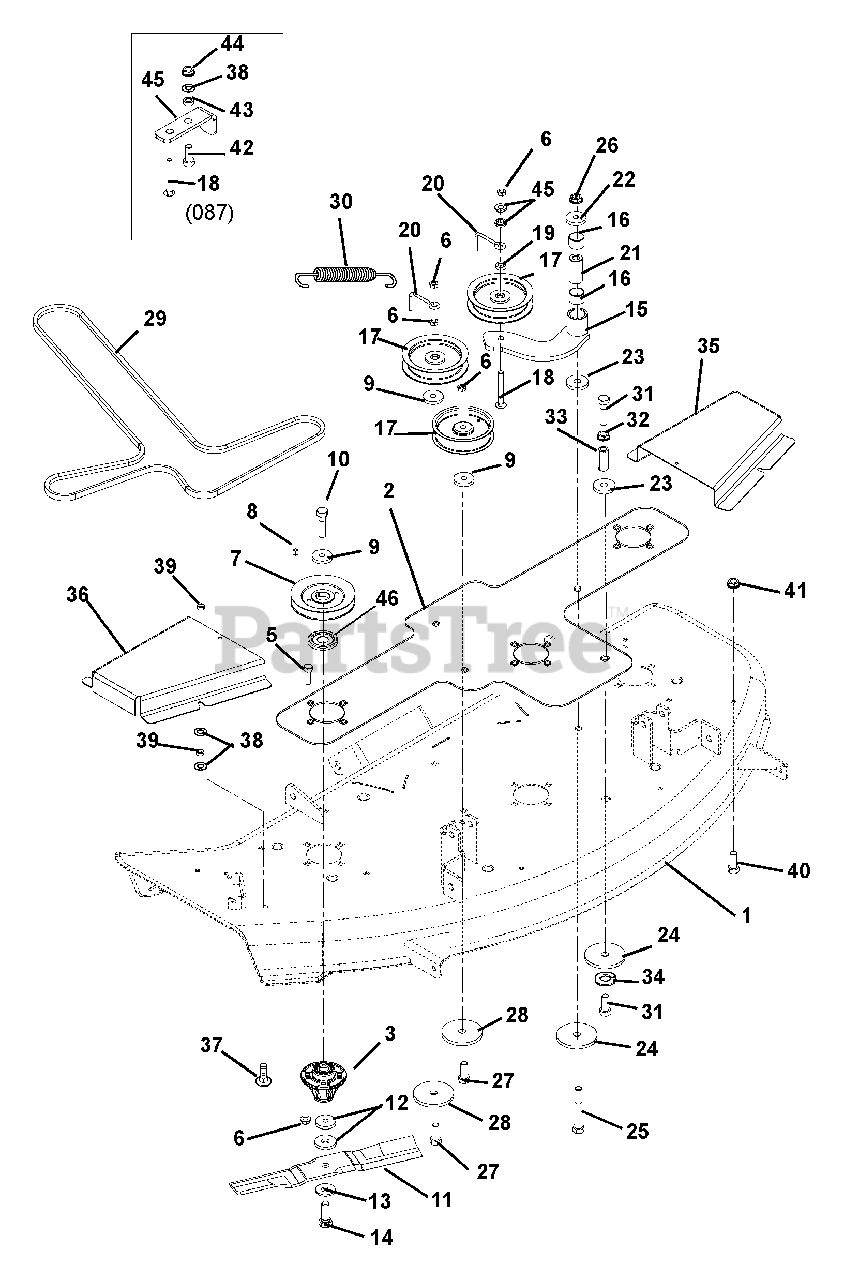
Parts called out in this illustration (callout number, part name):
1	WELDMENT, ZOOM 50" DECK
1	WELDMENT, 40" STAMPED DECK
2	50 DOUBLER PLATE, ZOOM
2	DOUBLER PLATE, ZOOM 40
3	SPINDLE ASSEMBLY
4	DUST CAP
5	@BLT-RDHDSQNK .38-16X1.25 G5YZ
6	@NUT-LK-NYL-FLG .38-16 YWZC
7	SHEAVE, 4.75 DIA A-SECTION
7	SHEAVE, 4.25 DIA A-SECTION
8	KEY, SQ .25 X .38 X .25
9	WSHR,FLT STL.406X1.50X.245YWZC
10	BLT-HEX .38-16X1.0 GR8 YZ EP30
11	BLADE
11	MOWER BLADE, 13.94"
12	WSHR-FLT .640X1.75X.250 YWZC
13	WSHR-BLVL .669X1.535X.138
14	BLT-HEX .62-18X1.75 GR8 YWZC
15	WMT, IDLER ARM
16	BRG, 1.00 X 1.12 X .75
17	IDLER, FLAT .38X4.00X1.06
18	@BLT-RDHDSQNK .38-16X3.50 G5YZ
18	@BLT-RDHDSQNK .38-16X2.50 G5YZ
19	BSHG-SLV .391X.688X.52 PM
20	BELT FINGER
21	BSHG, SPCR .502X.997X2.03 PM
22	WSHR-FL-STL.511X1.441X.125 YWZ
23	WSHR-FL-STL .515X1.625X.250 YZ
24	WASHER, FLAT .531X3.000X.25
25	@BLT-HEX .50-13X3.50 GR5 YWZC
26	@NUT-LK-TOP-FLG .50-13 YWZC
27	@BLT-HEX .38-16X2.75 GR5 YWZC
28	WSHR-FL-STL .469X2.00X.25 YWZC
29	V-BELT, A-WRAPPED
29	V-BELT, HA-WRAPPED
30	EXTENSION SPRING
31	@BLT-HEX .50-13X1.25 GR5 YWZC
32	NUT-SPNLK-FLG .50-13 YWZC
33	NUT, COUPLING 1/2-13X1.75 YWZC
34	@WSHR-LK .50X.125 REG YWZC
35	BELT COVER, LEFT
35	BELT COVER, LEFT ZOOM 40
36	BELT COVER, RIGHT
36	BELT COVER, RIGHT ZOOM 40
37	@BLT-RHDSHSQNK.31-18X1.25 G5YZ
38	@WSHR-FL-STL.38X.875X.083 YWZC
39	@NUT-LK-NYL-FLG .31-18 YWZC
40	@BLT-HEX .31-18X.75 GR5 YWZC
41	@NUT-SPNLK-FLG .312-18 YWZC
42	@BLT-HEX .38-16X1.00 GR5 YWZC
43	BSHG-SLV .377X.624X.235
44	@NUT-LK-TOP-FLG .38-16 YWZC
45	BELT FINGER
45	BSHG-FLG .406X.88X.270X.140
46	DUST CAP
